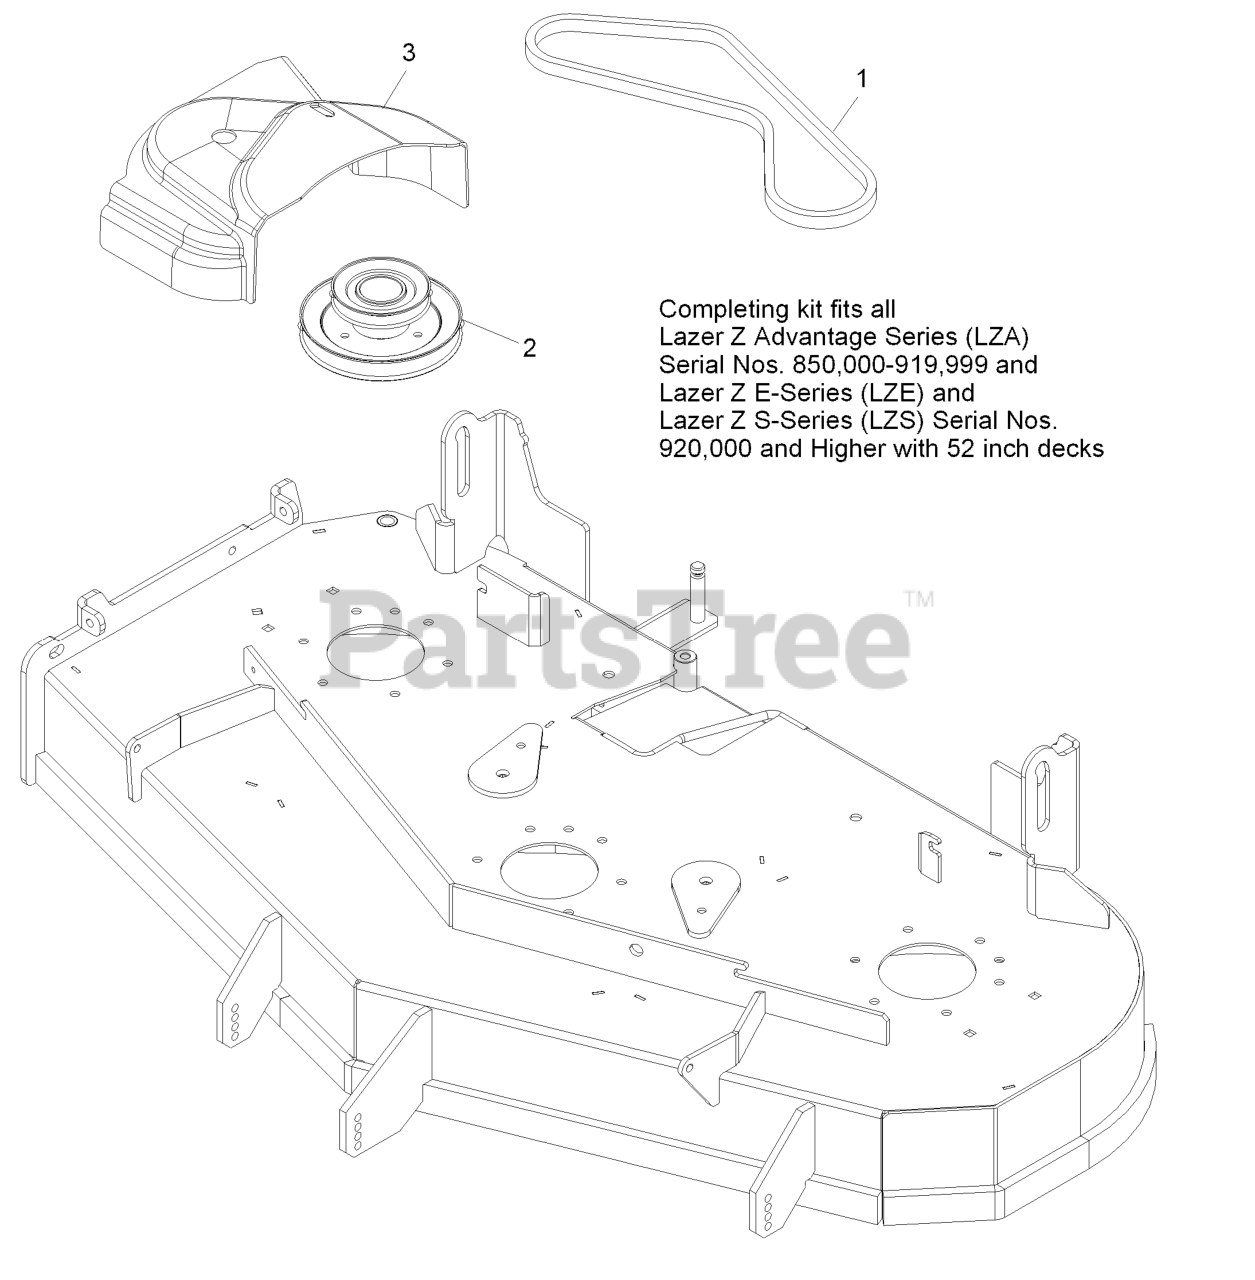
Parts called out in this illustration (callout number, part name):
1	Belt, Blower Drive 52
2	Jackshaft,Uv Drive 524 Splined
3	Cover,Belt Uv 52
